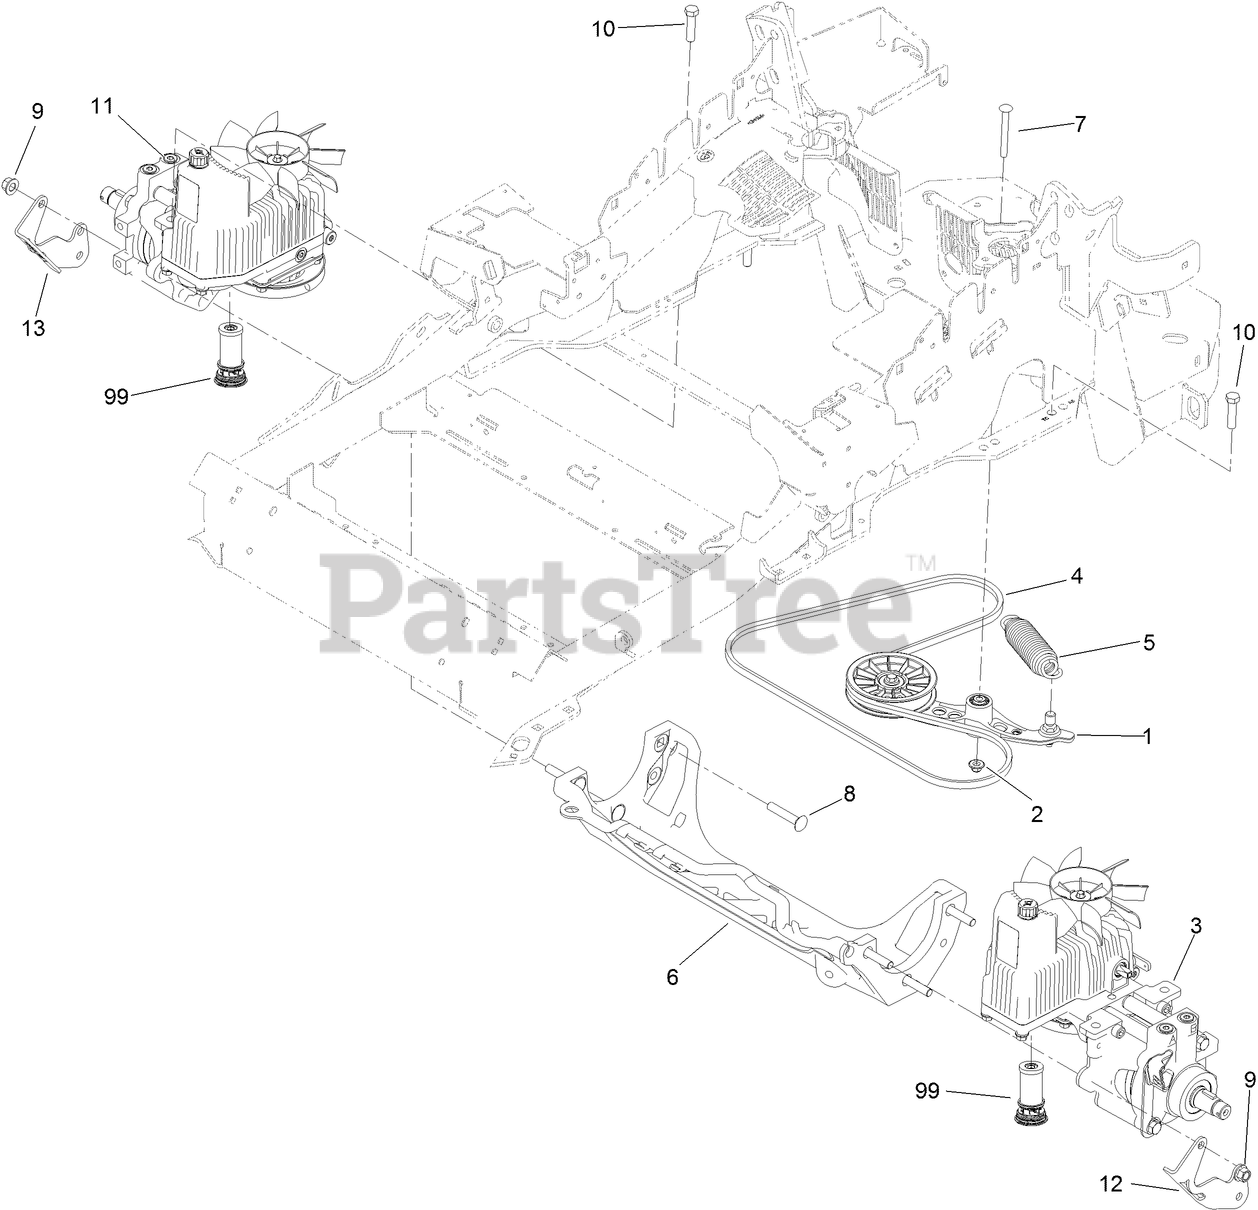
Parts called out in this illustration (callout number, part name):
1	PUMP IDLER ASM
2	NUT-FLANGE, NI
3	LH HYDRO ASM (12CC W/SHOCK)
4	BELT
5	SPRING-EXTENSION
6	CRADLE-HYDRO
7	BOLT-SHOULDER, CARRIAGE
8	SCREW-CARR
9	NUT-LOCK
10	SCREW-HH
11	RH HYDRO ASM (12CC W/SHOCK)
12	BRACKET-DISCHARGE MOUNT, LH
13	BRACKET-DISCHARGE MOUNT, RH
99	FILTER-HYDRO
